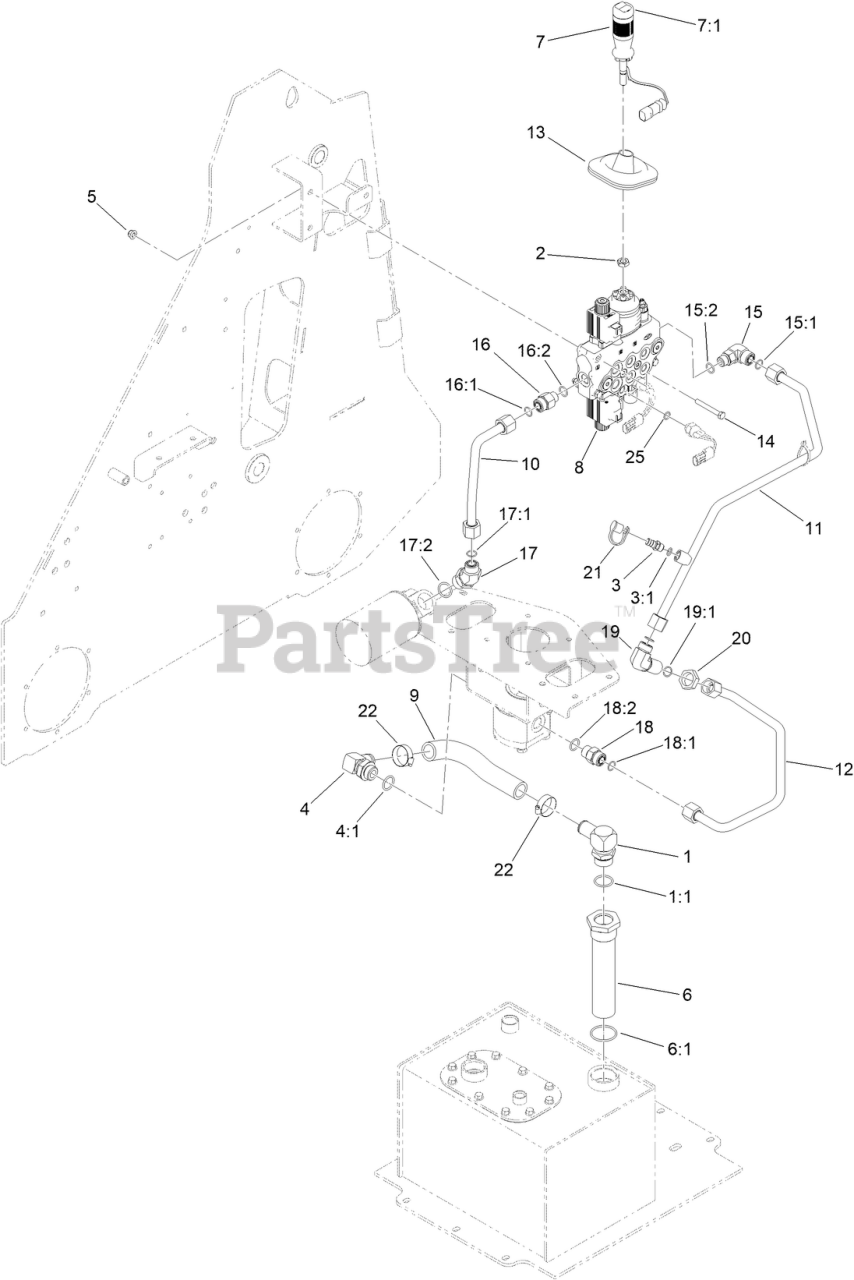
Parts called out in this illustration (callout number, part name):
1	STEM-BARB-90
1:1	O-RING
3	FITTING-DIAGNOSTIC
3:1	O-RING
4	FITTING-90
4:1	O-RING
5	NUT-HF, NI
6	STRAINER-IN TANK
6:1	O-RING
7	HANDLE-AUXILIARY ASM
7:1	BOOT-SWITCH, JOYSTICK
8	VALVE-HYD-LOADER
10	HYDRAULIC TUBE ASM
11	HYDRAULIC TUBE ASM
12	HYDRAULIC TUBE ASM
13	BOOT-JOYSTICK
14	SCREW-HH
15	FITTING-ELBOW, 90 DEG
15:1	O-RING
15:2	O-RING
16	FITTING-STRAIGHT
16:1	O-RING
16:2	O-RING
17	FITTING-ELBOW 45
17:1	O-RING
17:2	O-RING
18	FITTING-STRAIGHT
18:1	O-RING
18:2	O-RING
19	FITTING-BULKHEAD, 90 DEG
19:1	O-RING
20	NUT-LOCK, BULKHEAD
21	CAP-DUST, RUBBER
22	CLAMP-HOSE
25	O-RING
